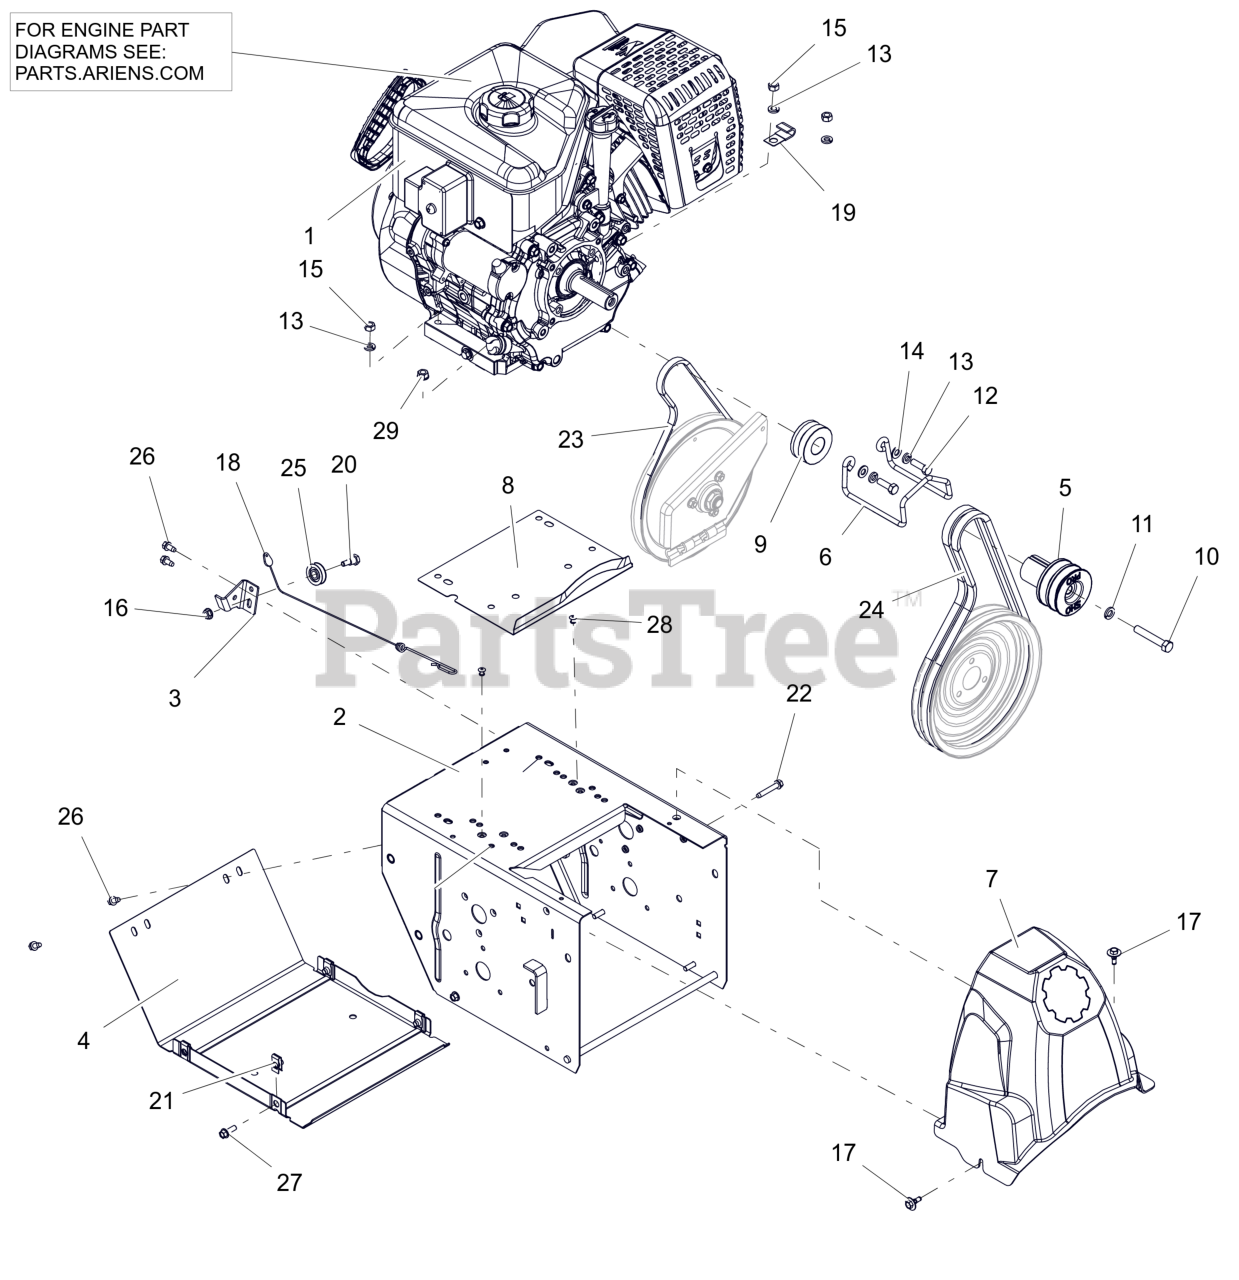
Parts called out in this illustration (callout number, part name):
1	ENGINE, EFI 369 GEN 3 240V/60W
2	FRAME, MAIN - 14GA DELUXE (ORANGE)
3	BRKT, CABLE PULLEY
4	COVER, BOTTOM
5	SHEAVE,ATTACHMENT-SHO 2 GRV
6	FINGER, BELT
7	COVER, BELT
8	BAFFLE, WATER - LARGE BLOCK
9	SHEAVE, TRACTION (KEYLESS)
10	BLT, HEX .38-24X2.25 G5 ZCC
11	WSHR,LK-REG .375X.094 ZCC
12	BLT, HEX 0.3125-24X1 G5 ZCC
13	WSHR, LK-HVY .312X.097 ZCC
14	WSHR,FLT .344X.688X.065 ZCC
15	NUT, HEX .312-18 ZCC
16	NUT-LK-TOP-FLG .250-20 GF ZCC
17	SCR-TAP .25-20X.5 CAPTIVE
18	CABLE, LOWER TRACTION,SS & PRO
19	J-CLAMP
20	BOLT, SHLDR -.375 X .375 X .25-20
21	NUT-RTNR .25-20X.56
22	SCR,TAP .25-20X1.50 HWH TR ZCC
23	V-BELT, 3L-WRAPPED
24	V-BELT, HA-RAW EDGE (SET)
25	PULLEY, CABLE
26	SCR-TAP .25-20X.50 HWH ZCC
27	BLT, HWH .25-20X.75 G5 ZCC
28	RVT, POP .1875 ZCC
29	NUT,LK-CTR-FLG .31-18 GF ZCC
